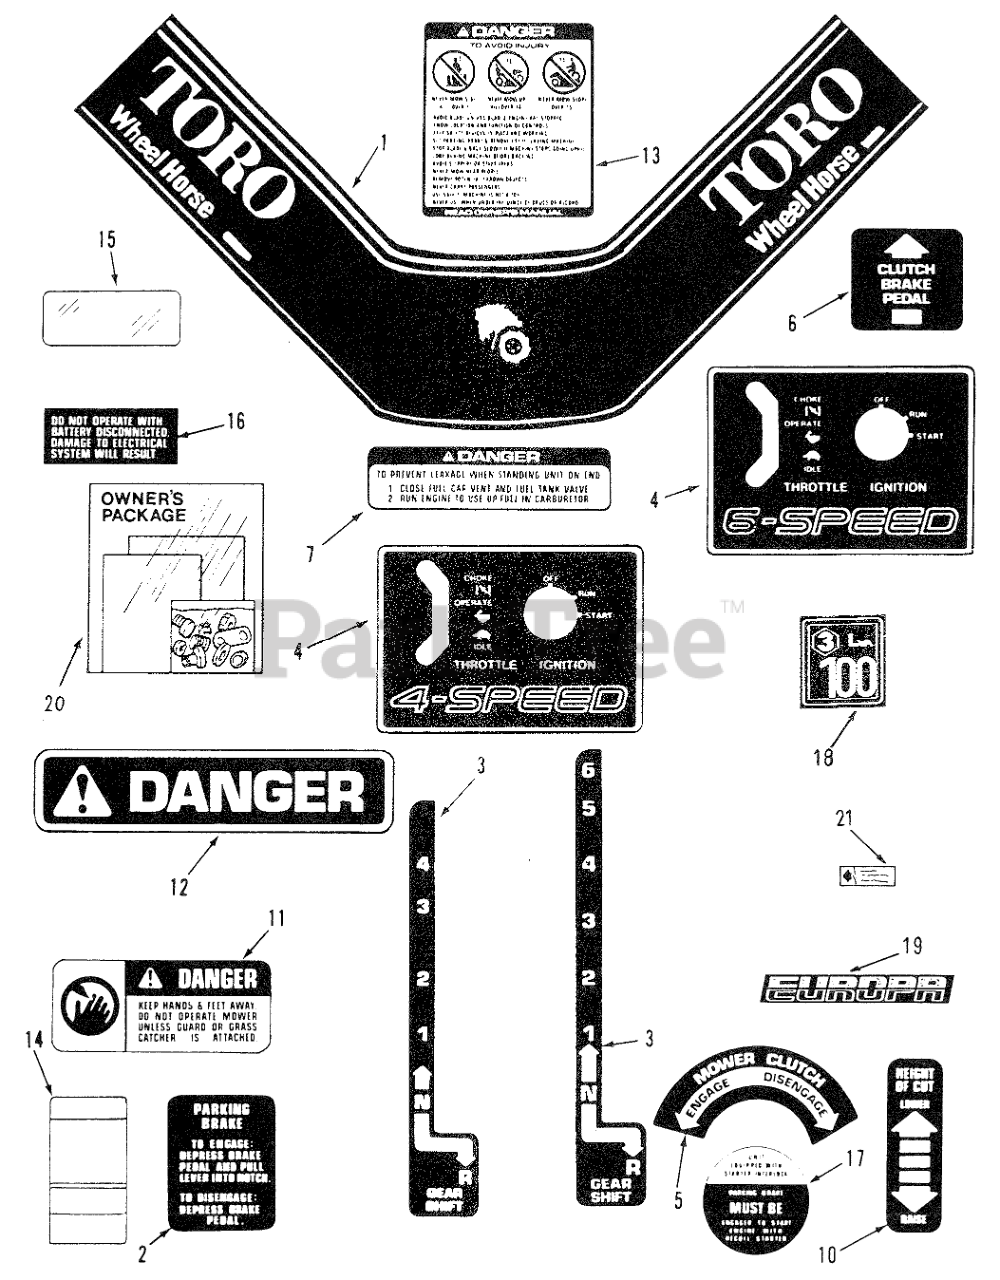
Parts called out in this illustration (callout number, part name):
1	DECAL-MODEL 110-4
2	DECAL PARKING BRAKE
3	DECAL SHIFT 4SPD
4	Ignition Throttle Decal Symbol 4-Speed
5	DECAL MOWER CLUTCH
6	DECAL CLUTCH & BRAKE
7	DECAL-DANGER
10	DECAL-HOC
11	Danger Decal
12	Danger Decal
13	DECAL-DANGER
14	MAINTENANCE-DECAL
15	DECAL-OVERLAY
16	DECAL ELECT SYSTEM
18	DECAL-EUROPE
21	DECAL-PTO BELT ADJ
